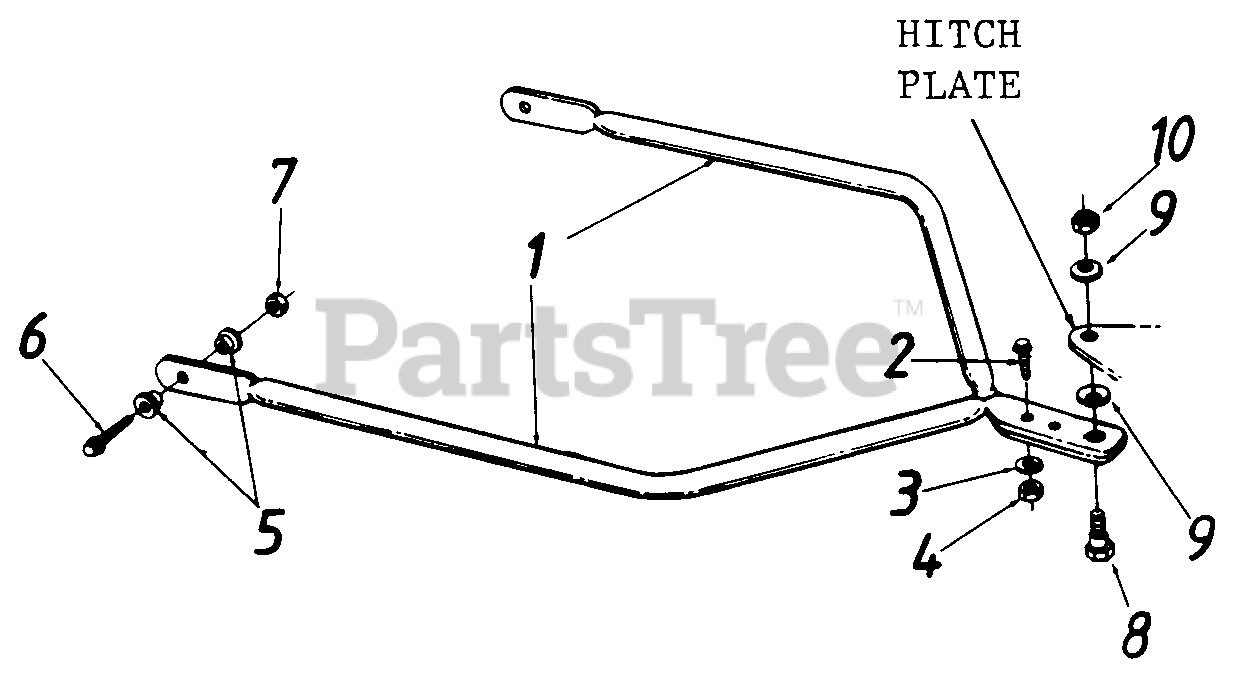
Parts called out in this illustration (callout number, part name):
3	L.-Wash. 1/4" I.D.
4	Hex Nut 1/4-20 Thd.
5	Shoulder Spacer
6	Hex Wash. Hd. Self-Tapp Scr. 5/16-18 x 1.0" 4.
7	Hex Nut 5/16-18 Thd.
8	Shoulder Bolt
9	Bell-Wash. .39" I.D. x 1.12" O.D.
10	Hex Top Jam Nut 3/8-16 Thd.
